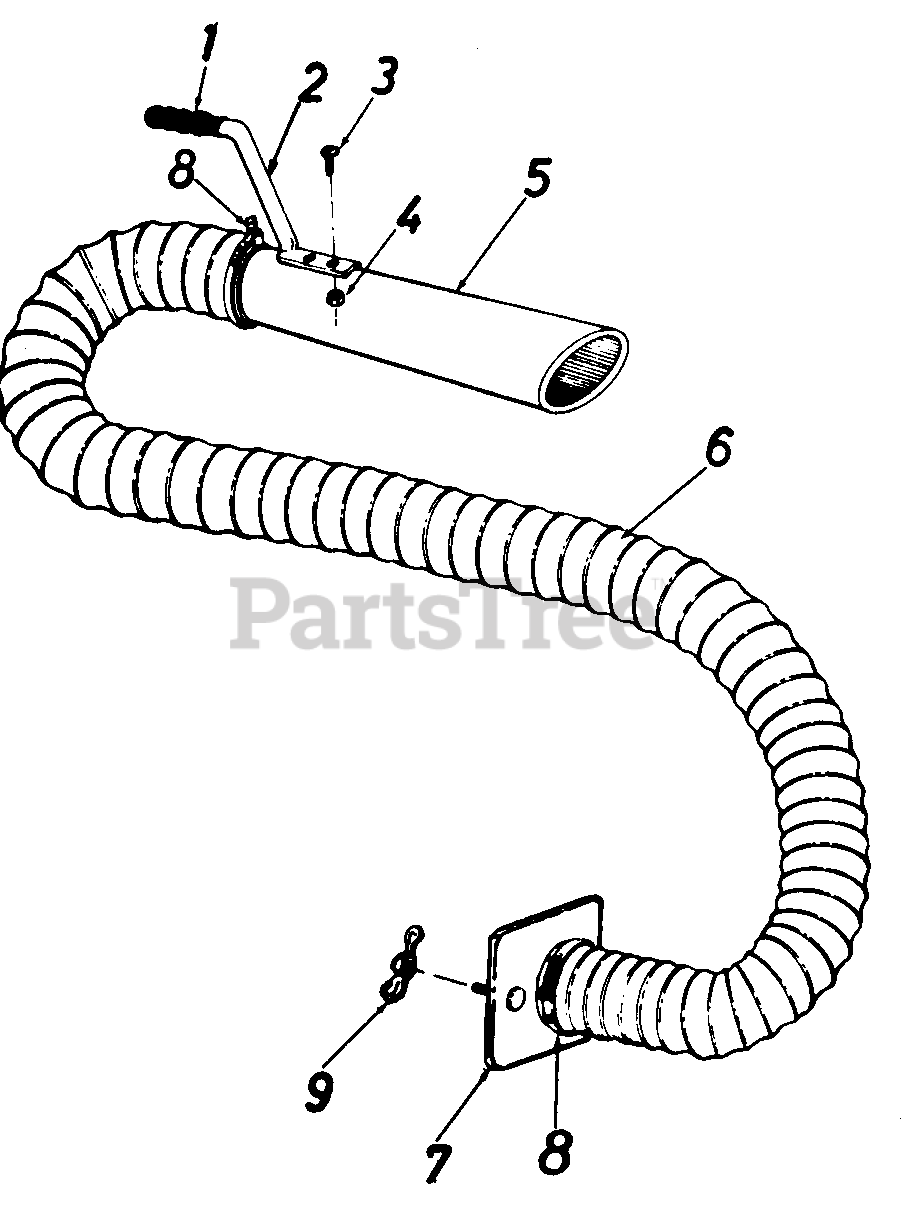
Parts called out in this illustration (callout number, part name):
1	Handle Grip
2	Handle
3	Truss Sems Scr. 10-24 x 1/2" Lg.*
4	Hex Nut 10-24 Thd.*
5	Hose Nozzle
6	Flexible Hose 4" Dia. x 10' Lg.
7	Hose Adapter Plate
8	Hose Clamp - For 4" Dia. Hose
9	Wing Nut 1/4-2 Thd.
